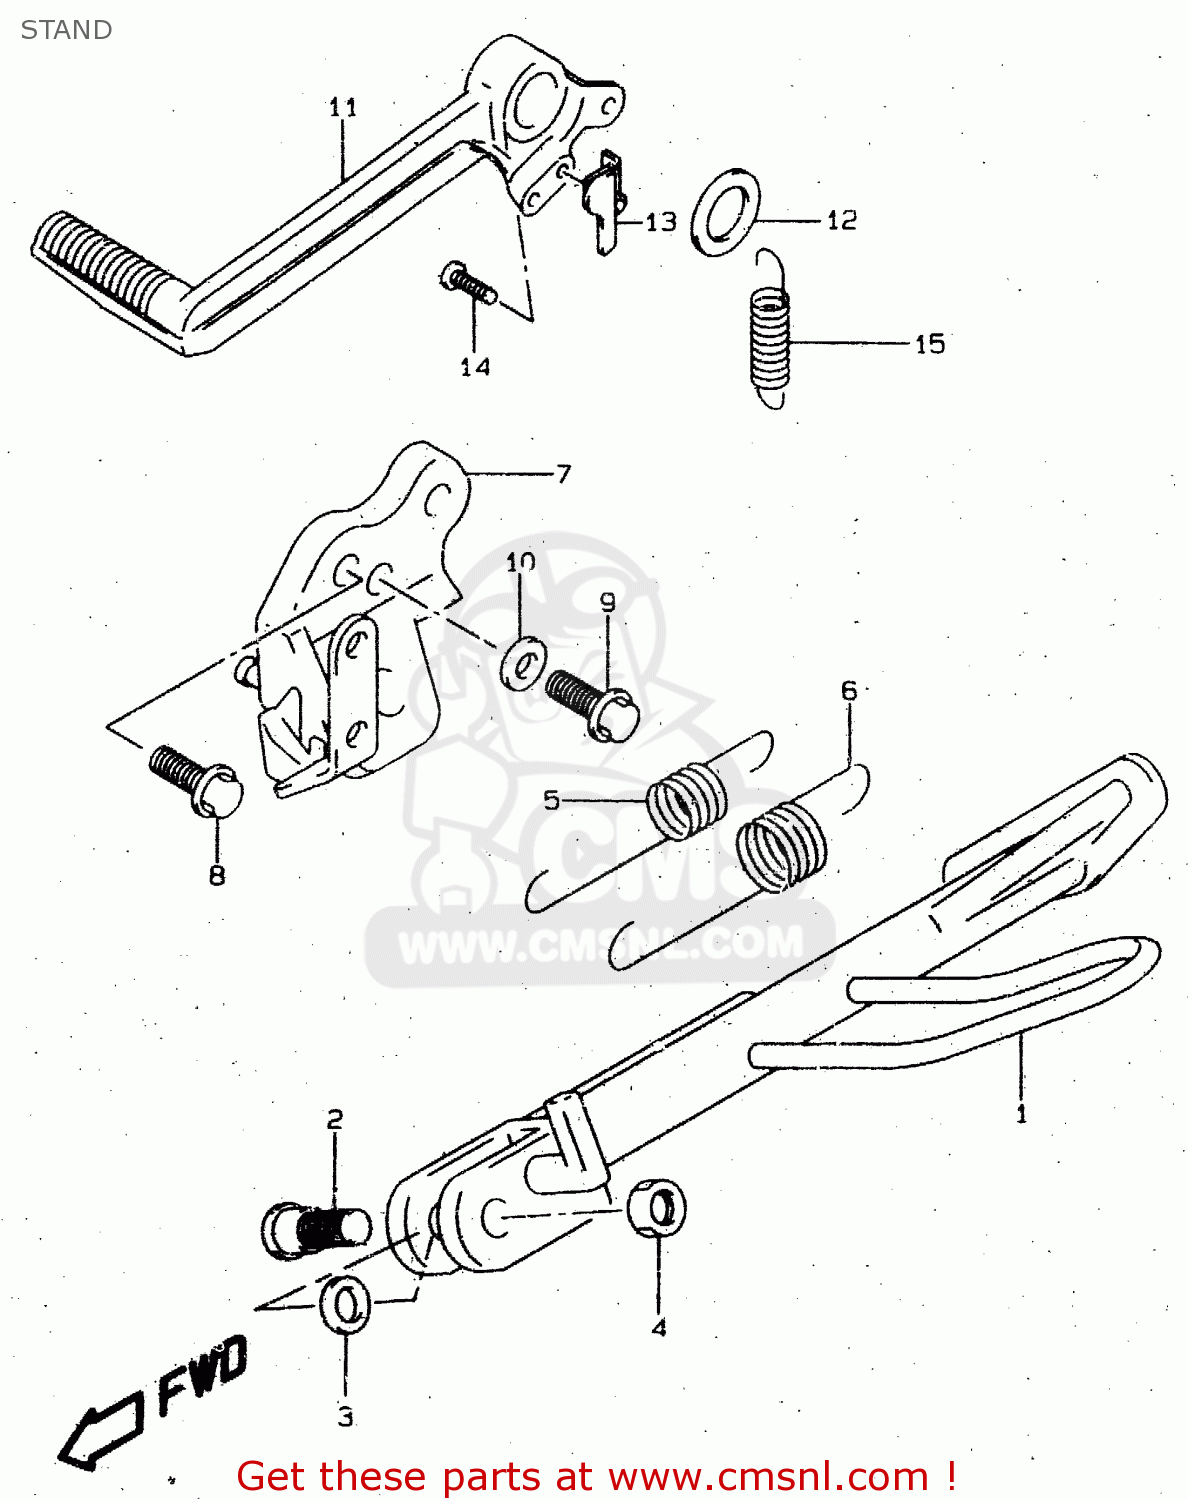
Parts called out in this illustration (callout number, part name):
1	STAND,PROP
2	BOLT(10X34)
3	SHIM
4	NUT
5	SPRING
6	SPRING
7	BRACKET,PROP STAND
8	BOLT
9	BOLT
10	WASHER
11	PEDAL,BRAKE
12	WASHER(18X24X1)
13	HOOK,RETURN SPRING
14	SCREW
15	SPRING
